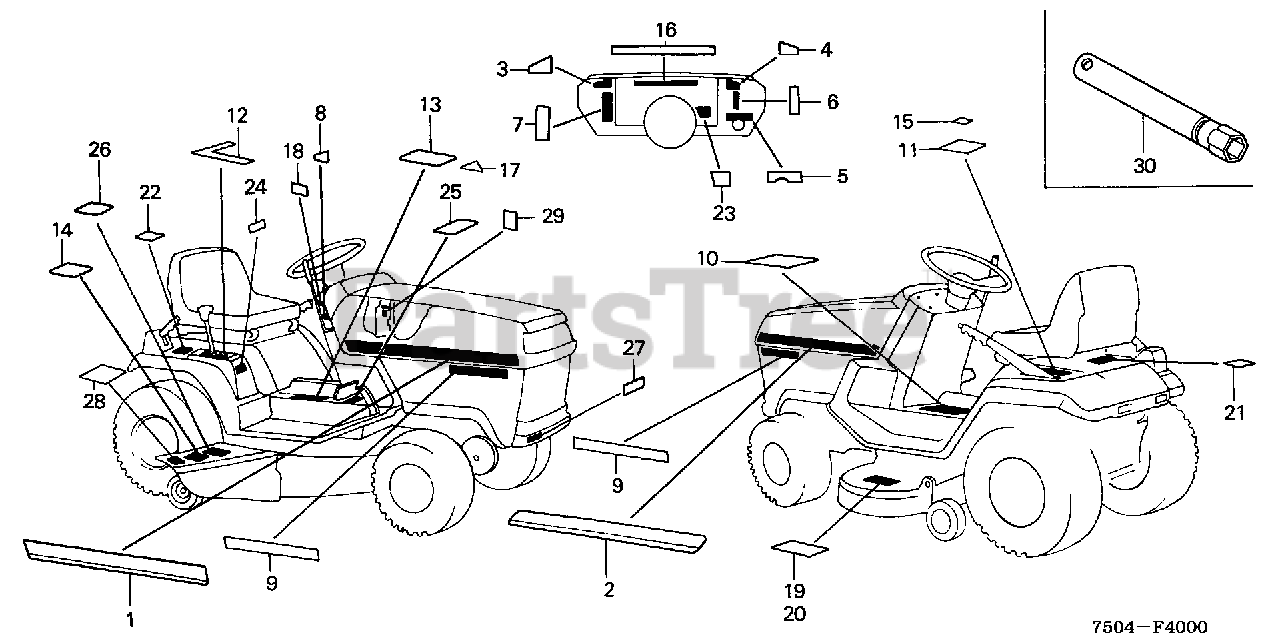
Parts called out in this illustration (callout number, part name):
1	MARK, R. SIDE STRIPE
2	MARK, L. SIDE STRIPE (NOT AVAILABLE)
3	MARK, THROTTLE
4	MARK, LIGHT SWITCH
5	MARK, ENGINE SWITCH
6	MARK B, LIGHT SWITCH
7	MARK, THROTTLE (ENGLISH)
8	MARK, P.T.O.
9	MARK, HOOD (NOT AVAILABLE)
10	LABEL B, OPERATION (NOT AVAILABLE)
11	MARK, ADJUSTING LEVER (NOT AVAILABLE)
12	MARK, SHIFT GUIDE (NOT AVAILABLE)
13	LABEL A, OPERATION (NOT AVAILABLE)
14	LABEL, DANGER
15	MARK, INDICATOR
16	MARK A, PARKING BRAKE
18	MARK, P.T.O. CLUTCH
19	LABEL A, WARNING
21	LABEL, FUEL WARNING
22	LABEL B, PARKING BRAKE
23	MARK, OVERHEAT CAUTION
27	LABEL, BELT CAUTION (E)
29	MARK, OIL CAUTION
